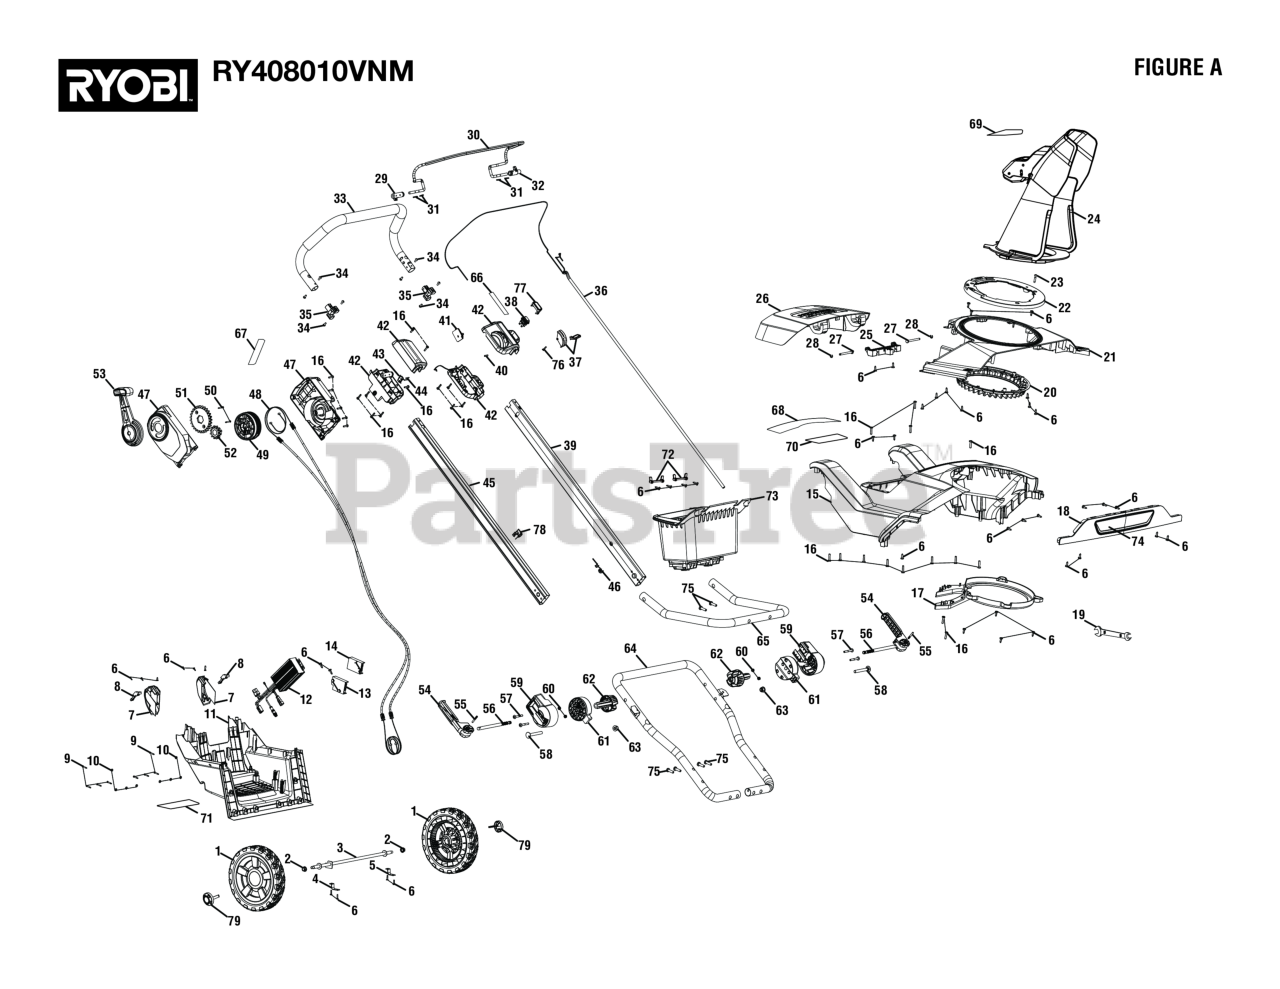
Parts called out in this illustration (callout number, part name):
1	11 in. Wheel Assembly
2	Blade Nut (M10 x 1.25, Hex Flange Hd.)
3	Rear Axle
4	Right Rear Axle Press Plate
5	Left Rear Axle Press Plate
6	Screw (M4.2 x 12 mm, T20 Torx Pan Hd.)
7	Shoulder Assembly
8	Knuckle Assembly
9	Screw (M4 x 22 mm Pan Hd.)
10	Rubber Washer
11	Bottom Cover (Inc. Key No. 71)
12	Brushless Motor Controller
13	Controller Mouting Other Side
14	Controller Mouting
15	Top Cover
16	Screw (M4 x 18 mm, T20 Torx Pan Hd. S.T.)
17	Rotation Gear Cover
18	Front Cover
19	12 mm Wrench
20	Chute Gear
21	Rear Cover
22	Chute Rotation Bezel
23	Screw (M4 x 20 mm, Pan Hd.)
24	Chute Assembly
25	Battery Cover Spring Support
26	Battery Cover
27	Hinge Shaft
28	Retaining Ring (4 mm)
29	Spring Side Actuator
31	Spring Pin (3 x 16 mm)
32	Switch Side Actuator
33	Upper Handle and Foam Grip Assembly
34	Screw (M4 x 9 mm, T20 Torx Pan Hd.)
36	Electrical Wire Assembly
37	Speed Control Assembly
38	Center Switch
39	Right Tube
40	Dial Lever Insert
41	Potentiometer Control Board Assembly
42	Actuator Housing Assembly
43	Micro Switch
44	Switch Pin
45	Left Tube
46	Line Buckle
47	Chute Adjustment Assembly
48	Cable Assembly
49	Upper Cable Drum Assembly
50	Screw (M3 x 22 mm, T10 Torx Pan Hd.)
51	Lever Gear
52	Upper Drum Gear
53	Chute Adjustment Lever
54	Knuckle Cam Latch
55	Cam Lever Dowel (4 mm)
57	Screw (M5 x 38 mm, T25 Torx Truss Hd.)
58	Carriage Bolt (M8 x 1.25 in.)
59	Knuckle Assembly
61	Handlebar Cleat
63	Flange Lock Nut (M8 x 1.25 mm)
64	Internal Bracing Bar Tube
65	Lower Support Tube
66	Starting Instructions Label
67	Chute Rotation Label
68	Icons/Danger/Caution Label
69	Chute Warning Icons Label
70	Battery Notice Label
71	Data Label
72	Terminal Block Holder
73	Battery Box Assemblyx
74	Light Bar
75	Screw (1/4-15 x 3/4 in., T30 Torx Pan Hd.)
76	Screw (M x 12 mm, Pan Hd.)
77	Start Button
78	Line Buckle
79	Wheel Hub Cap
